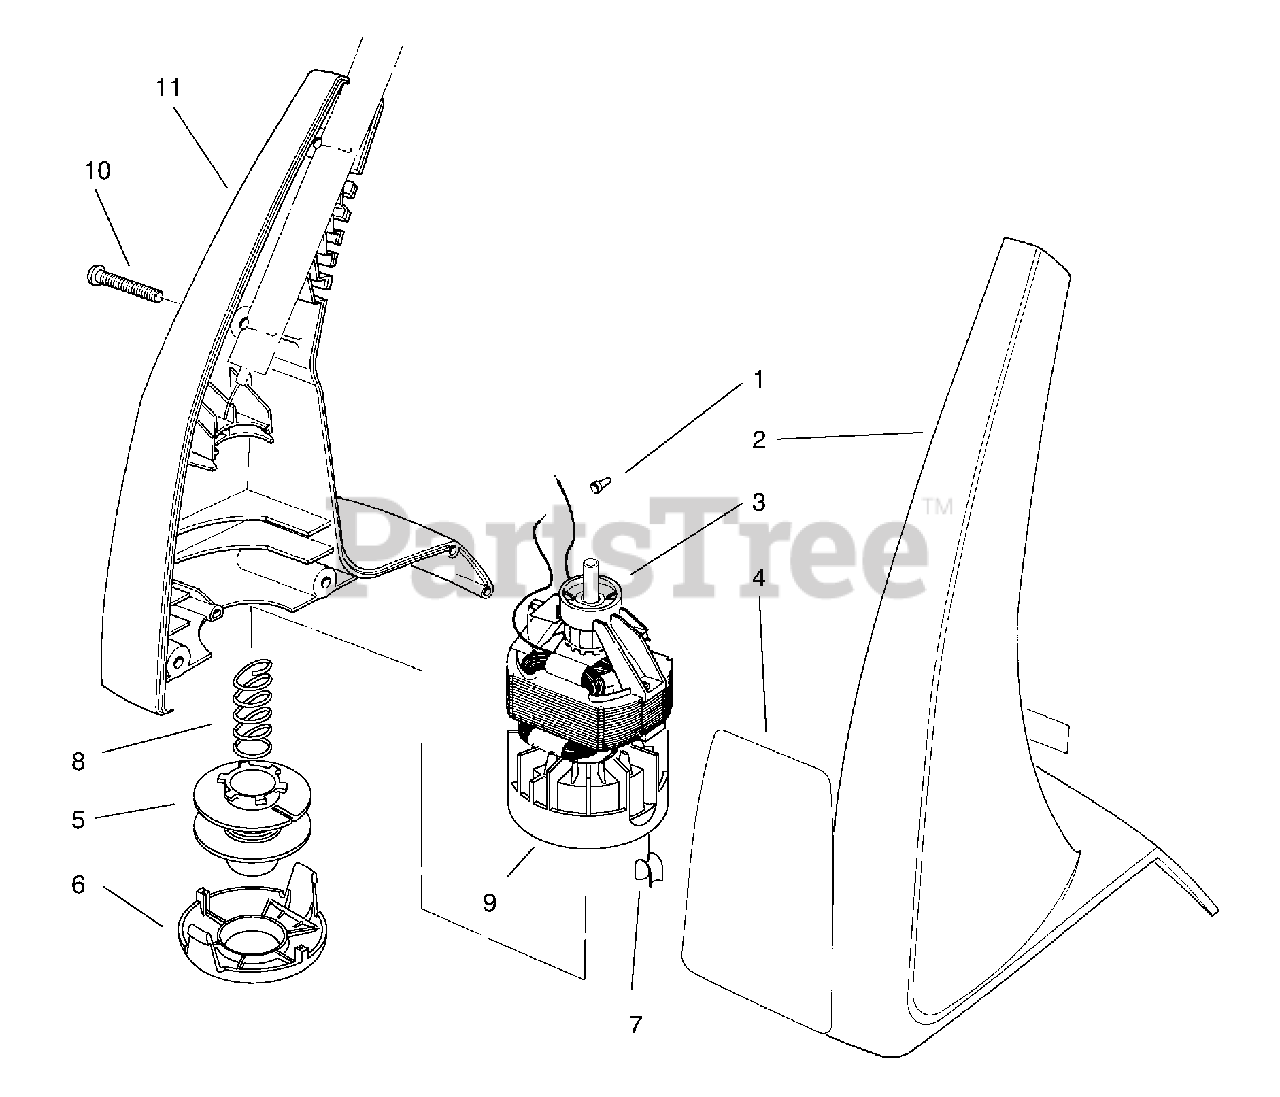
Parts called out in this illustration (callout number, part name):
1	Connector-Wire
2	Housing-L.H.
3	Motor Assembly (Incl. Ref. #7 & 9 )
5	Empty Spool
9	Drum
11	Housing Assembly-R.H.
